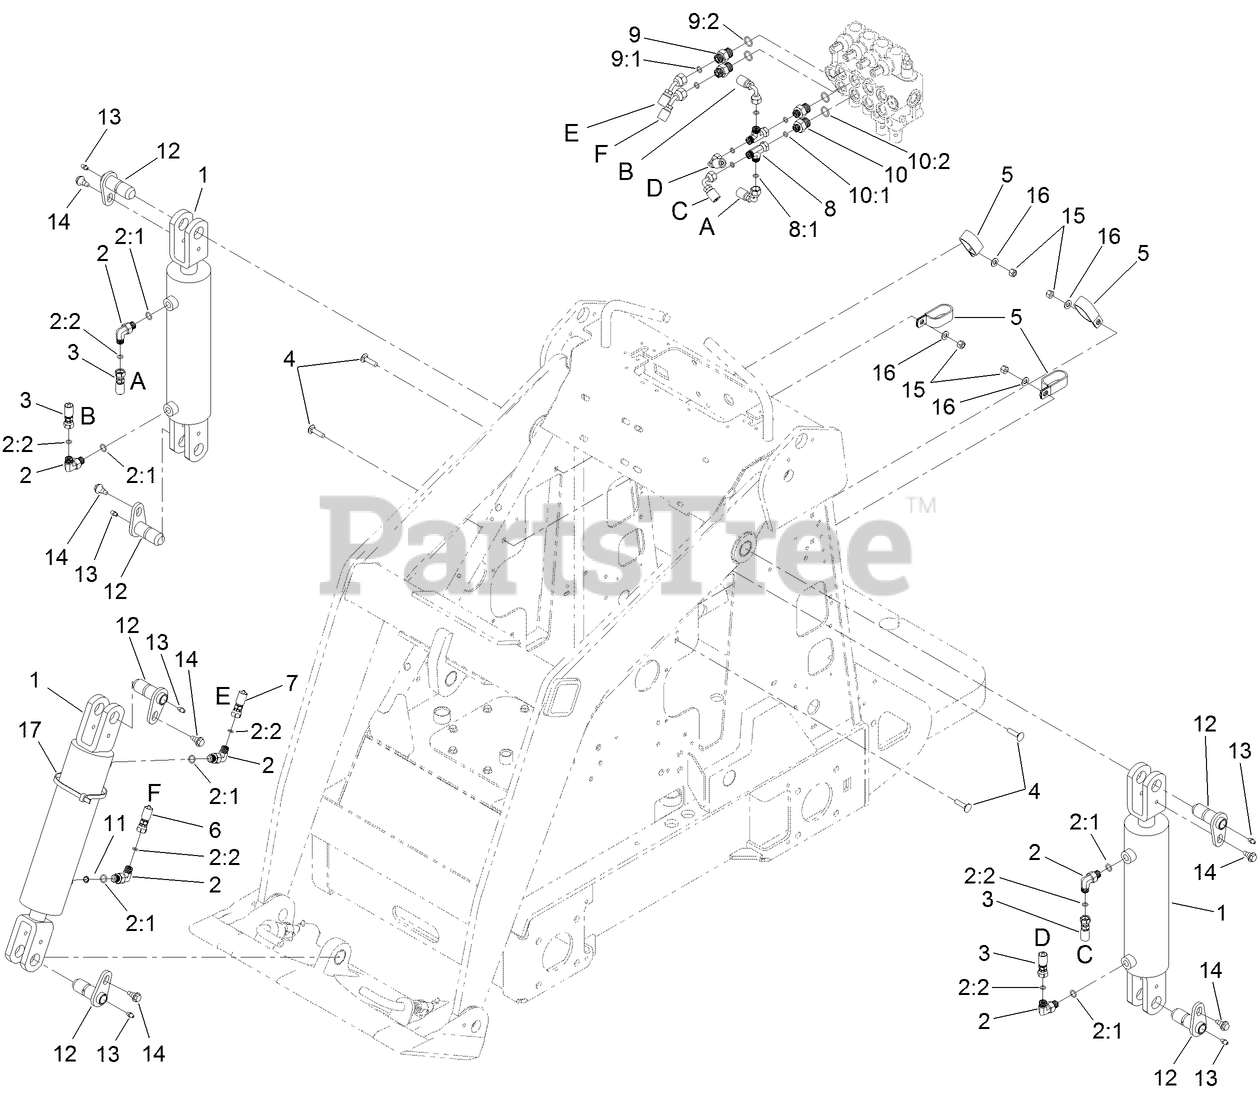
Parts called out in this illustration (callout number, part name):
1	CYLINDER-HYD
2	FITTING-ELBOW, 90 DEG
2:1	O-RING
2:2	O-RING
3	HOSE-HYD
4	SCREW-CARR
5	CLAMP-R, DOUBLE
6	HOSE-HYD
7	HOSE-HYD
8	FITTING-HYD
9	FITTING-STRAIGHT
9:1	O-RING
9:2	O-RING
10	FITTING-STR
10:1	O-RING
10:2	O-RING
11	ORIFICE-PORT INSERT, ONE WAY
12	PIN-PIVOT
13	FITTING-GREASE
14	BOLT-SHOULDER
15	NUT-LOCK, NI
16	WASHER-PLAIN
17	TIE-CABLE
